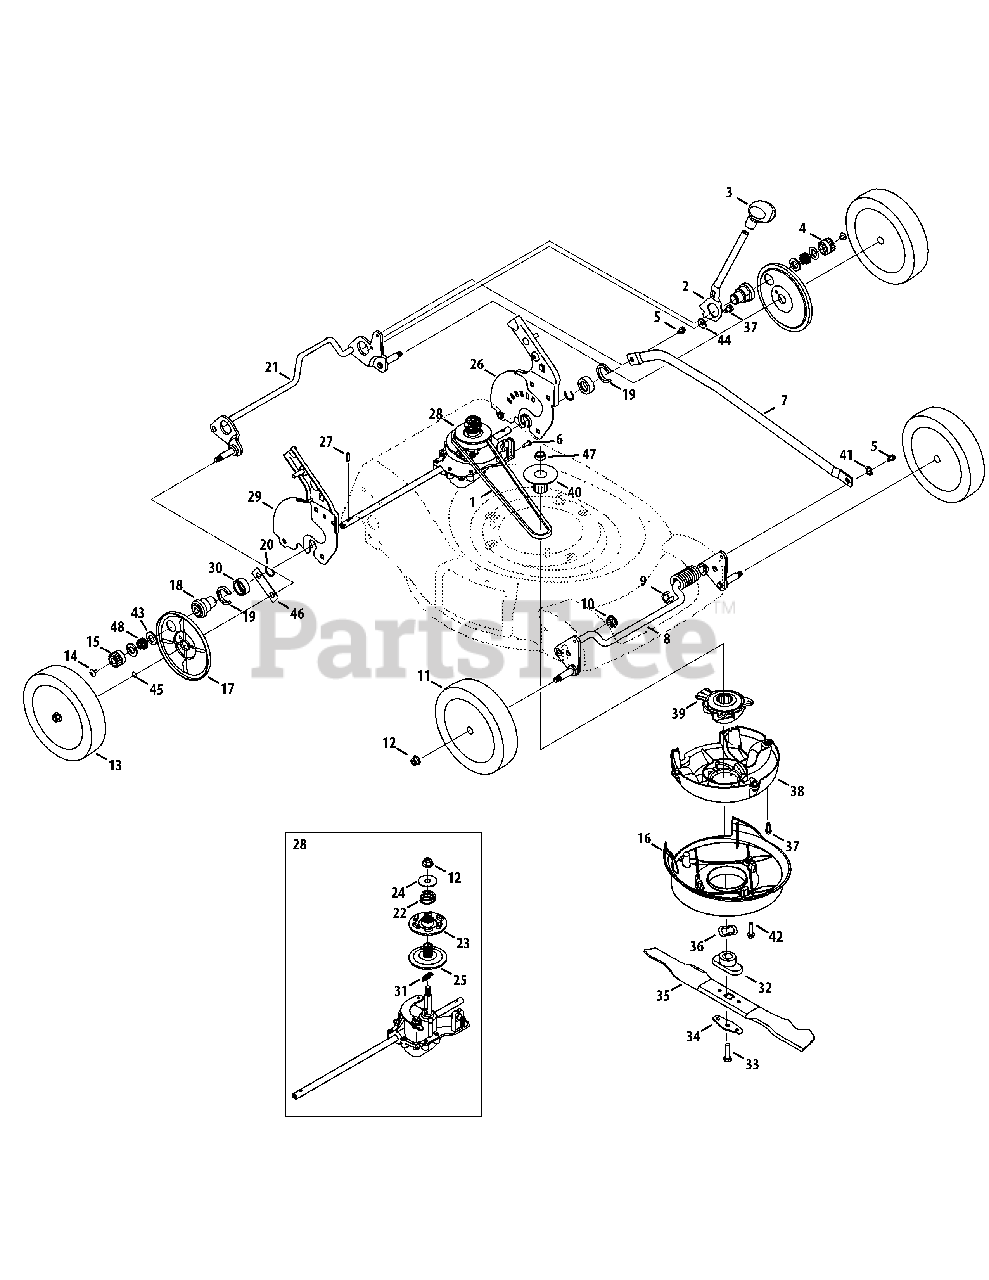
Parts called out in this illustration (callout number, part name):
2	Spring Lever
4	Spur Gear, 14T - LH
5	Shldr. Screw, 1/4-20 x 0.50
6	Screw, 1/4-15 x .750
8	Front Bracket Assembly
9	Clip Spacer
10	Split Hex Flange Bearing
11	Front Wheel
12	Flange Lock Nut, 3/8-16
13	Rear Wheel
14	Screw, 1/4-20 x .39
15	Spur Gear, 14T - RH
17	Wheel Dust Cover
18	Transmission Bearing Support
19	Clip Spacer
20	Retaining Ring .875
21	Rear Bracket Assembly
22	Compression Spring
23	Upper Pulley
24	Washer, Flat, .442 x 1.38 x .060
25	Lower Pulley
26	Handle Bracket Assembly LH
27	Dowel Pin
28	Transmission Assembly
29	Handle Bracket Assembly RH
30	Bearing Support Spacer
31	Extension Spring
32	Blade Adapter
33	Screw, 3/8-24 x 1.50
34	Blade Bell Support
35	21" Mulching Blade
36	Washer, Wave, .88 x 1.31 x .029
37	TT Screw, 1/4-20 x .500
38	Engine Baffle
39	Lower Pulley Assembly
40	Pulley, Half
41	Washer, Wave, .385 x .598
42	Screw, 1/4-15 x 1.250
43	Washer, Flat, .508 x 1.00 x .020
44	Washer, Bell, .340 x .872 x .080
45	Ring, .375ID x .054
46	Gear Retainer Strap
47	Spcr., 7/8 x 1.265
48	Spring, Wave
